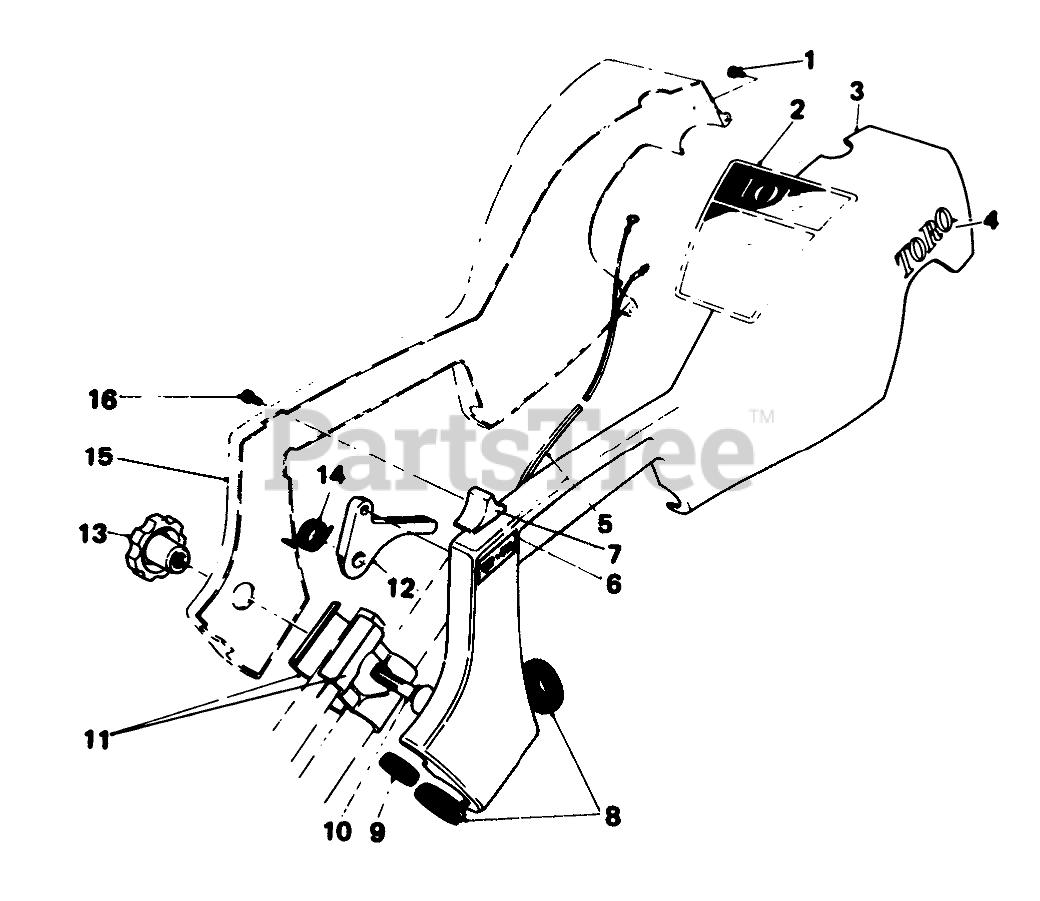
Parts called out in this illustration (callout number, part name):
2	Toro Decal Trimmer/Weeder
3	Engine Housing L.H.
4	DECAL - TORO
5	Wiring Harness
6	Decal Kill Switch
7	SWITCH COVER-BLACK
8	GROMMET
9	GROMMET
10	BOLT-CARR
11	Bracket-Handle Support
12	Throttle Lever
14	Spring Torsion
15	Engine Housing R.H.
16	Screw
